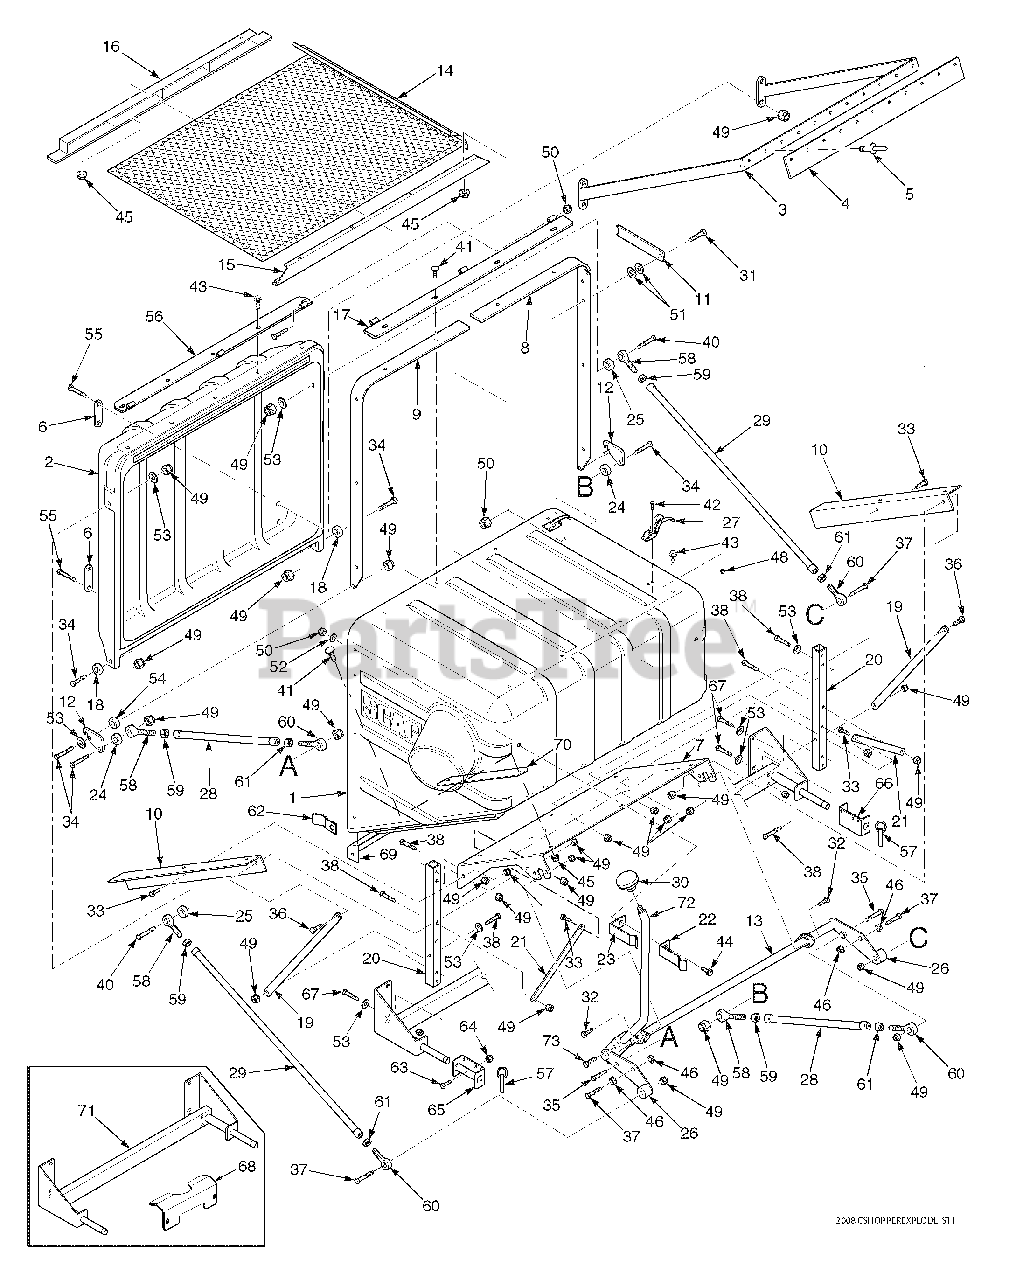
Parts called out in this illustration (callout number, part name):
1	Hopper, GC-STT-CS
2	Door, GC-CS
3	Sweeper Weldment, GC-CS
4	Pad, Rubber
5	Pop Rivet, 3/16 x .652
6	Plate, Stiffener
7	Support Frame, Hopper
8	Hinge Bracket, LH
9	Hinge Bracket, RH
10	Bracket, Hopper Support
11	Latch, Door Prop
12	Plate, Latch
13	Bellcrank Weldment, Lever
14	Debris Screen Weldment
15	Screen Support Weldment, Rear
16	Screen Support Weldment, Front
17	Hinge Weldment, Hopper
18	Spacer
19	Brace Stiffener, Short
20	Tube, Upright
21	Brace, Engine Mount
22	Latch, Dump Rod Inner
23	Latch, Dump Rod Outer
24	Spacer
25	Spacer
26	Spacer
27	Latch, Hood
28	Linkage Assembly, Lower
29	Linkage Assembly, Upper
31	Bolt, Hex Head 5/16-18 x 1-1/4"
32	Bolt, Hex Head 3/8-16 x 3/4"
33	Bolt, Hex Head 3/8-16 x 1"
34	Bolt, Hex Head 3/8-16 x 1-1/2"
35	Bolt, Hex Head 3/8-16 x 1-3/4"
36	Bolt, Hex Head 3/8-16 x 1-1/4"
37	Bolt, Hex Head 3/8-16 x 2"
38	Bolt, Hex Head 3/8-16 x 2-1/4"
39	Bolt, Hex Head 5/16-18 x 3-1/2"
40	Bolt, Hex Head 3/8-16 x 3-1/2"
41	Bolt, Carriage 5/16-18 x 1"
42	Screw, #10-32 x 1/2"
43	Cap Screw, 5/16-18 x 3/4" Serr. Flan.
44	Cap Screw, 5/16-18 x 1" Serr. Flan.
45	Nut, 5/16-18 Serrated Flange
46	Nut, 3/8-16 Serrated Flange
47	Nut, 3/8-16 UNC Jam
48	Nut, #10-32 Elastic Stop
49	Nut, 3/8-16 Elastic Stop
50	Nut, 5/16-18 Elastic Stop
51	Washer, Special Wave
52	Washer, 5/16-.375 x .875 x .083 Flat
53	Washer, 3/8-.931 x .938 x .105 Flat
54	Bushing, Hopper Latch GC-CS
55	Bolt, Hex Head 3/8-16 x 3"
56	Hinge Weldment, Door
58	Rod End Male, 3/8-24 LH Thread
59	Nut, 3/8-24 UNF LH Thread
60	Rod End Male, 3/8-24 RH Thread
61	Nut, 3/8-24 UNF RH Thread
62	Alignment Bracket, GC-CS
63	Bolt, Hex Head 3/8-16 x 1"
64	Nut, 3/8-16 Elastic Stop
65	Hitch Bracket Weldment
66	Hitch Bracket Weldment, Floating
67	Bolt, Hex Head 3/8-16 x 3-3/4"
68	Support Bracket, Catcher
69	Bracket, Lower Stiffener
70	Retainer Strip, Hopper
71	Frame Weldment
72	Rod, Dump Lever
73	Bolt, Hex Head 5/16-18 x 1-3/4"
